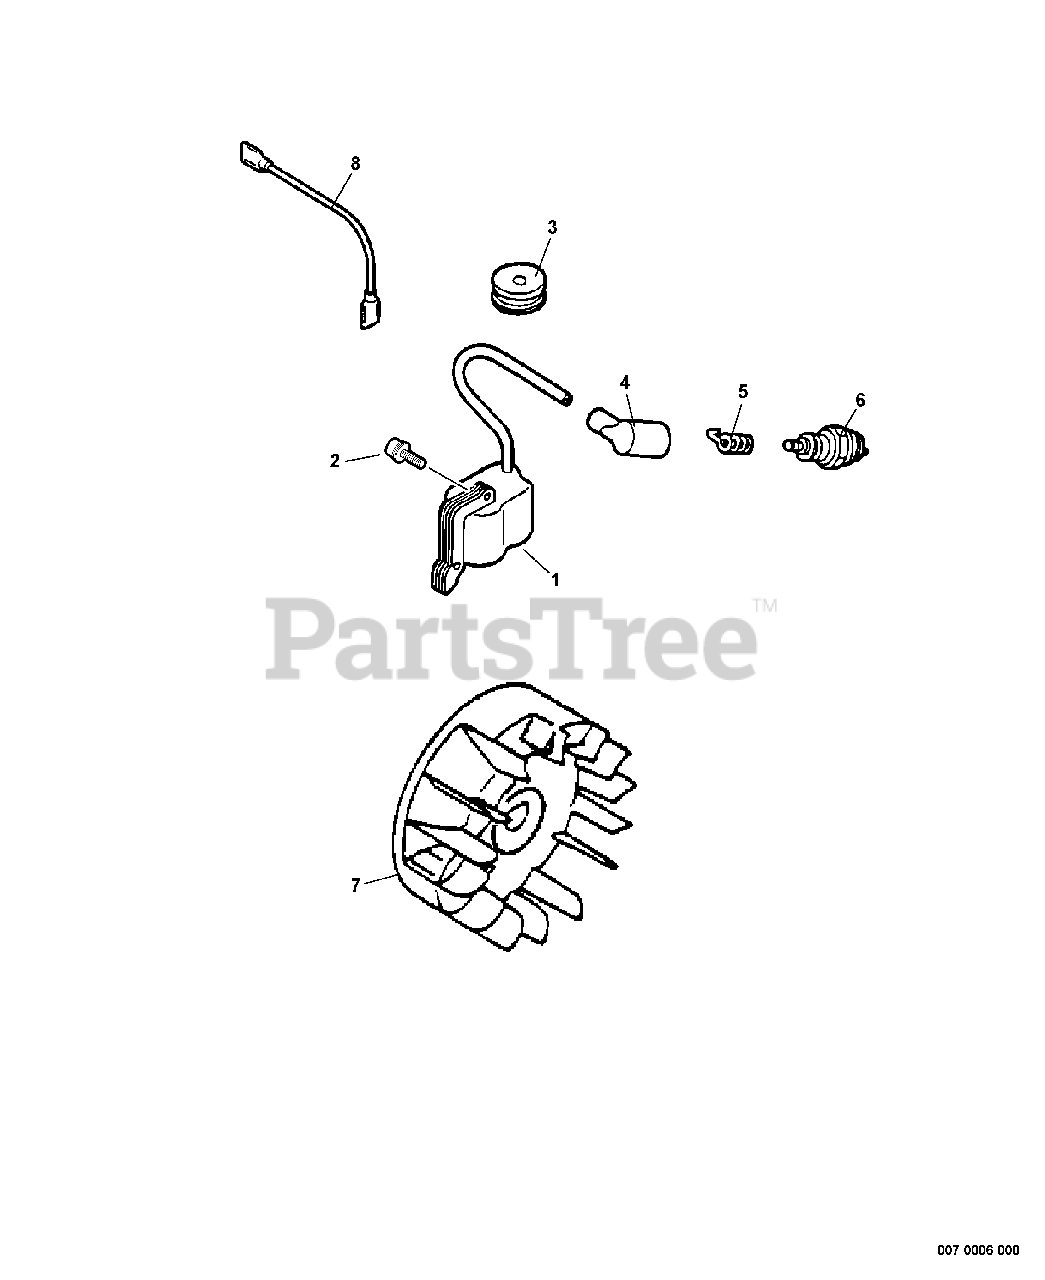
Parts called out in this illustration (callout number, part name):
1	COIL, IGNITION
2	SCREW - 4X22
3	GROMMET
4	CAP, SPARK PLUG
5	TERMINAL, SPARK PLUG CAP
6	SPARK PLUG -- BPM-7A
7	FLYWHEEL
8	LEAD - IGNITION
